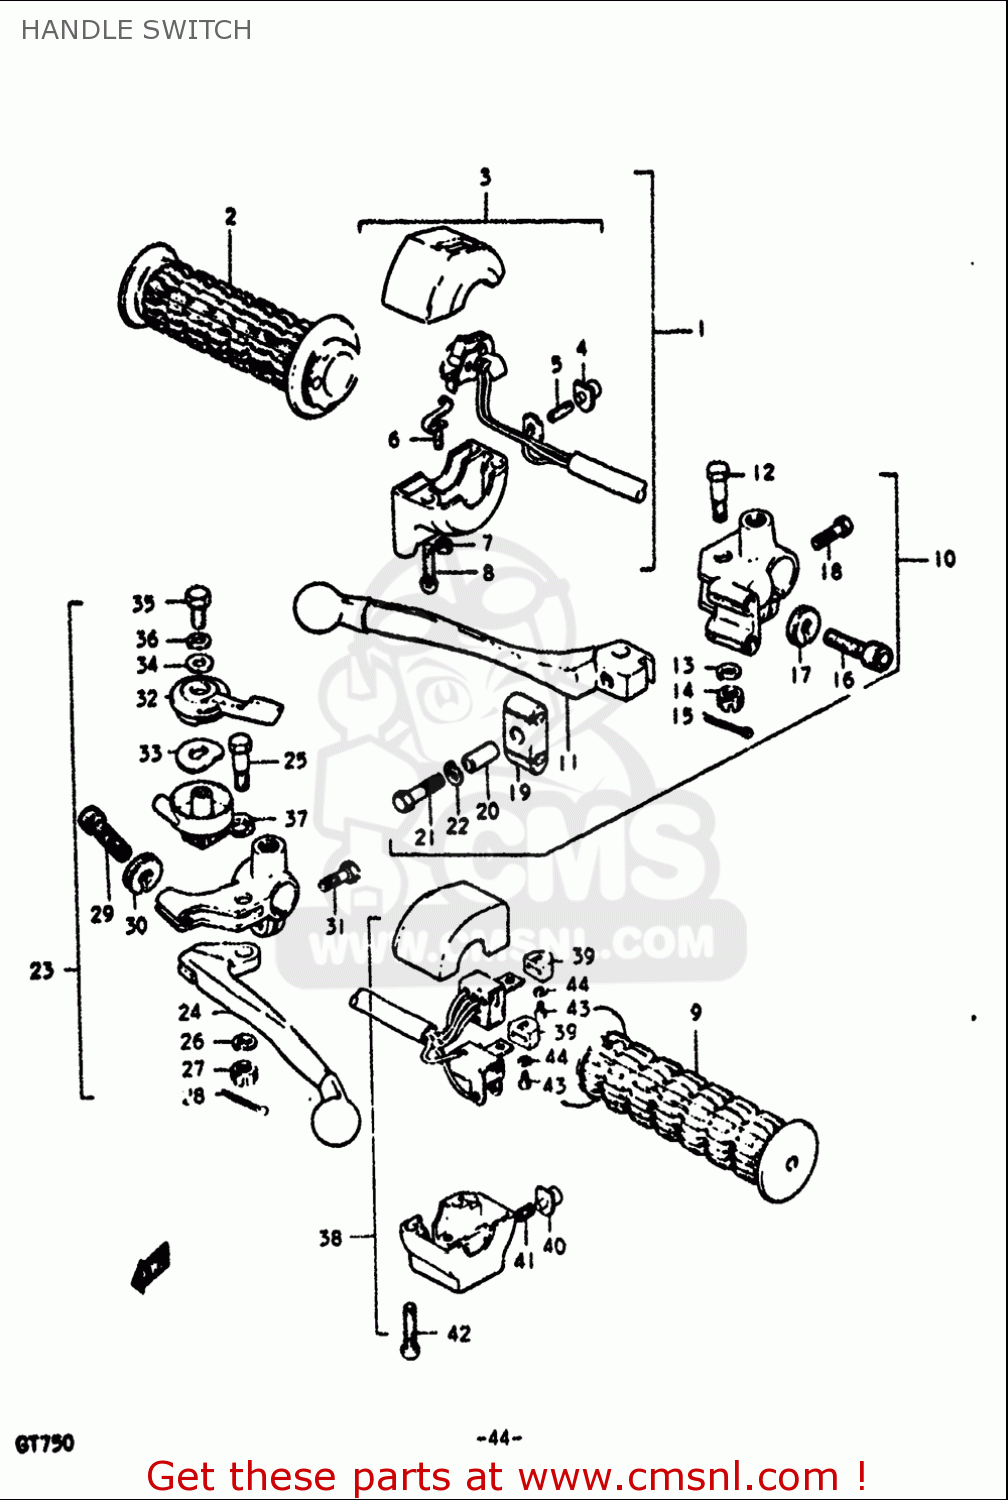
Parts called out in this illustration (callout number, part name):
1	GRIP ASSY,THROTTLE
2	GRIP,THROTTLE
4	BUTTON
5	SPRING
6	ADJUSTER, THROTTLE
7	NUT
8	SCREW
9	GRIP
10	SWITCH ASSY,HANDLE,R
12	BOLT,LEVER PIVOT
13	WASHER,LOCK
14	NUT,LEVER FITTNG
15	PIN 16X20
16	ADJUSTER,CABLE
17	NUT,CABLE ADJUSTER
18	BOLT
22	WASHER,LOCK
24	LEVER,CLUTCH
25	BOLT,LEVER PIVOT
26	WASHER,LOCK
27	NUT,LEVER FITTNG
28	PIN 16X20
29	ADJUSTER,CABLE
30	NUT,CABLE ADJUSTER
31	BOLT
32	LEVER
33	WASHER,ADJUSTER
34	WASHER(6.5X16X1)
35	BOLT
36	WASHER,LOCK
39	KNOB,HANDLE SWITCH,UPPER
40	BUTTON,HORN
41	SPRING,BUTTON
42	SCREW(5X27)
43	SCREW
44	WASHER,LOCK
